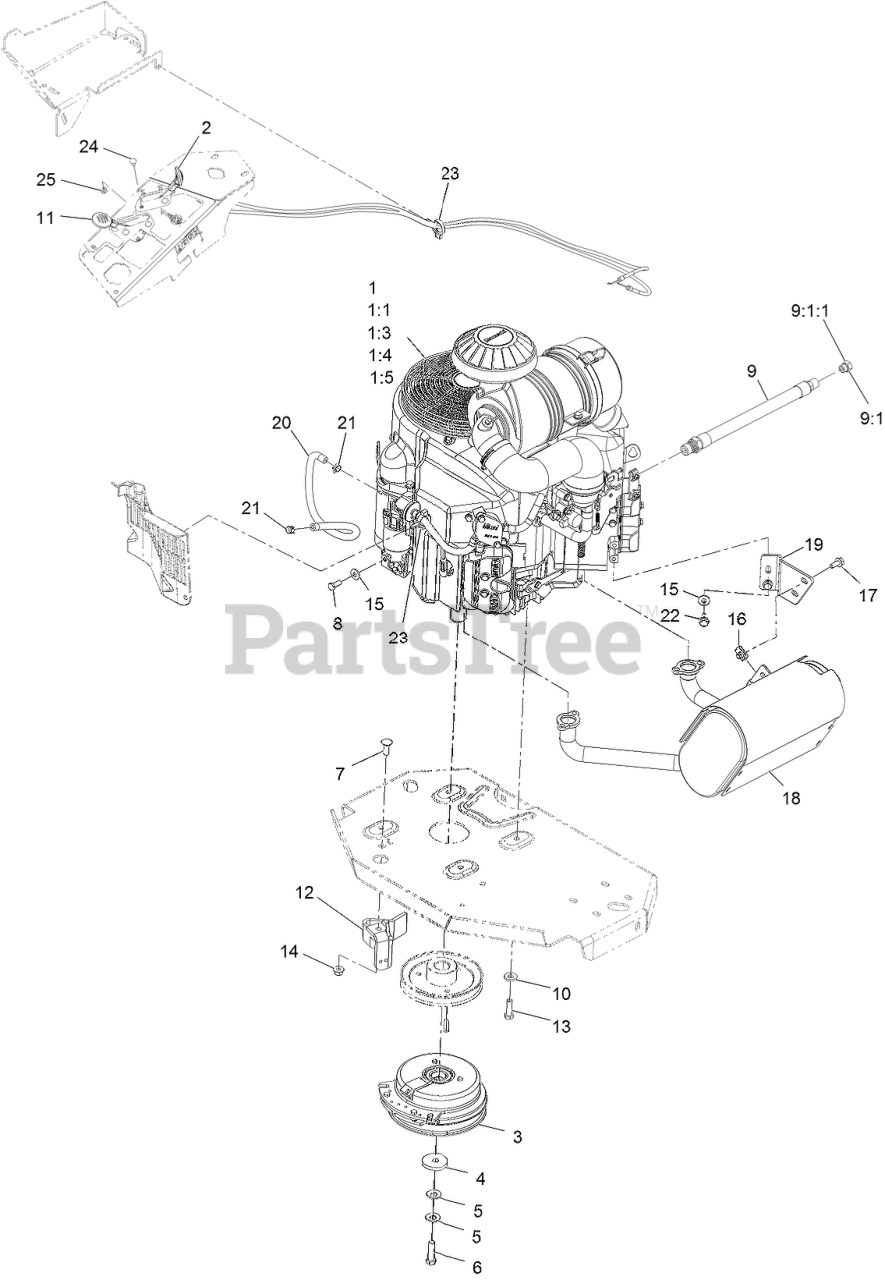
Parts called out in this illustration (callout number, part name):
1:1	Kawasaki 49065-2078 Engine Oil Filter
1:3	Kawasaki 49019-0031 Fuel Filter
1:4	Kawasaki 11013-7039 Safety Filter
1:5	Kawasaki 11013-7038 Air Filter
2	ASM, CHOKE CABLE
3	CLUTCH KIT
4	WASHER-CLUTCH
5	WASHER-SPRING
6	SCREW-HH 7/16-20 X 1 1/2 W/LOCTITE
7	SCREW-CARR
8	SCREW-HH
9	ENGINE OIL DRAIN HOSE ASM
9:1	PLUG-HH
9:1:1	O-RING
10	WASHER-BELLEVILLE
11	ASM,THROTTLE CABLE
12	CLUTCH-ANCHOR
13	SCREW-HH
14	NUT-HF, NI
15	WASHER-SPRING
17	SCREW-HHF
18	KIT, MUFFLER
19	BRACKET-MUFFLER
20	HOSE-FUEL
21	CLAMP-HOSE
22	SCREW-HHF
23	CLAMP-HOSE
24	BOLT-CARR
25	NUT-LOCK, NI
